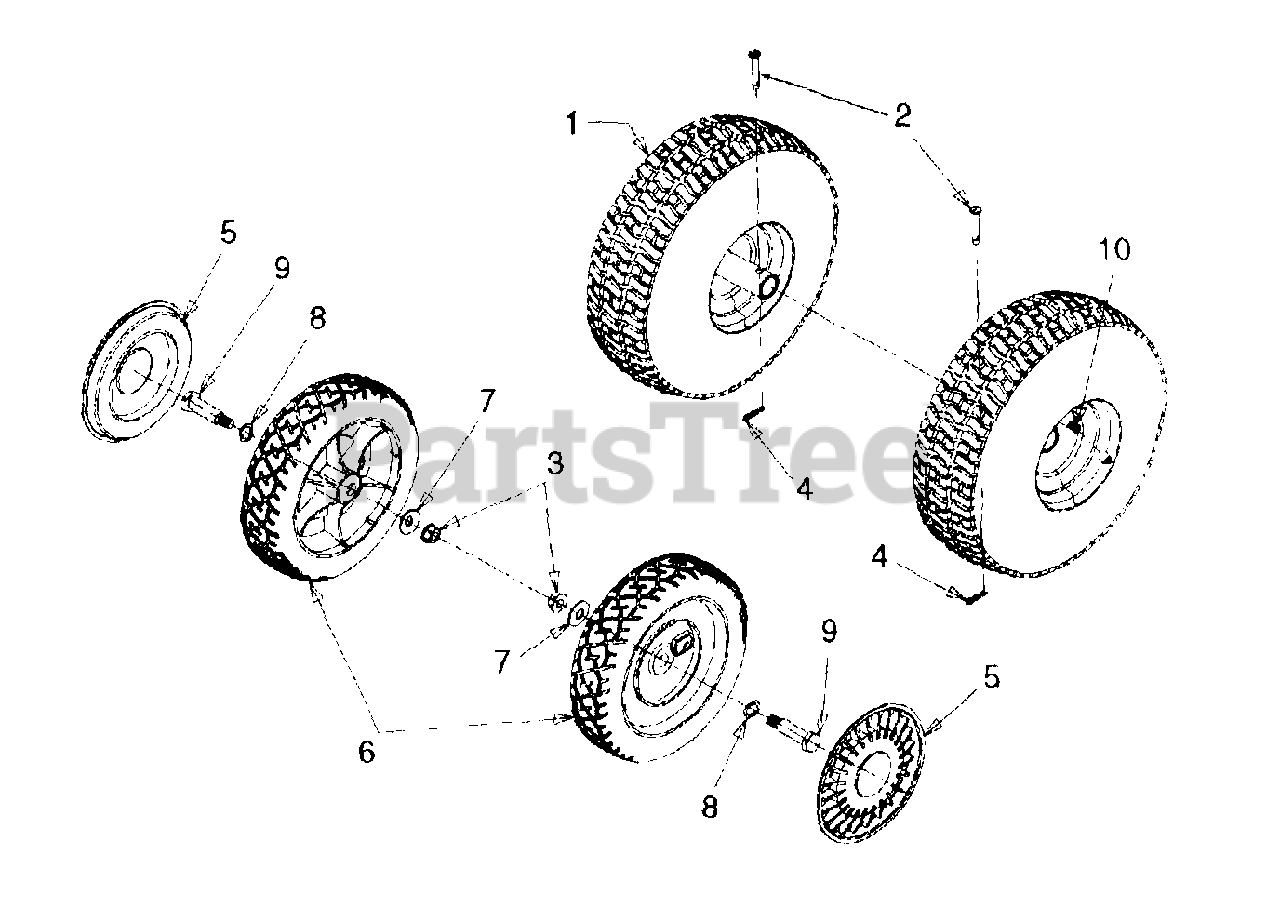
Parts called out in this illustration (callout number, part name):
1	Wheel Ass'y Complete
2	Pin, Clevis, .25 x 1.53
3	Nut, Hex Flange Lock, 3/8-16
4	Pin, internal Cotter
5	Hubcap, Beige
6	Wheel Ass'y Complete, 8 x 2.0
7	Washer, Bell, .401 x .870 x .06
8	Washer, Wave, .53 x .78 x .013
9	Shoulder Bolt
10	Valve, Tubeless Air
